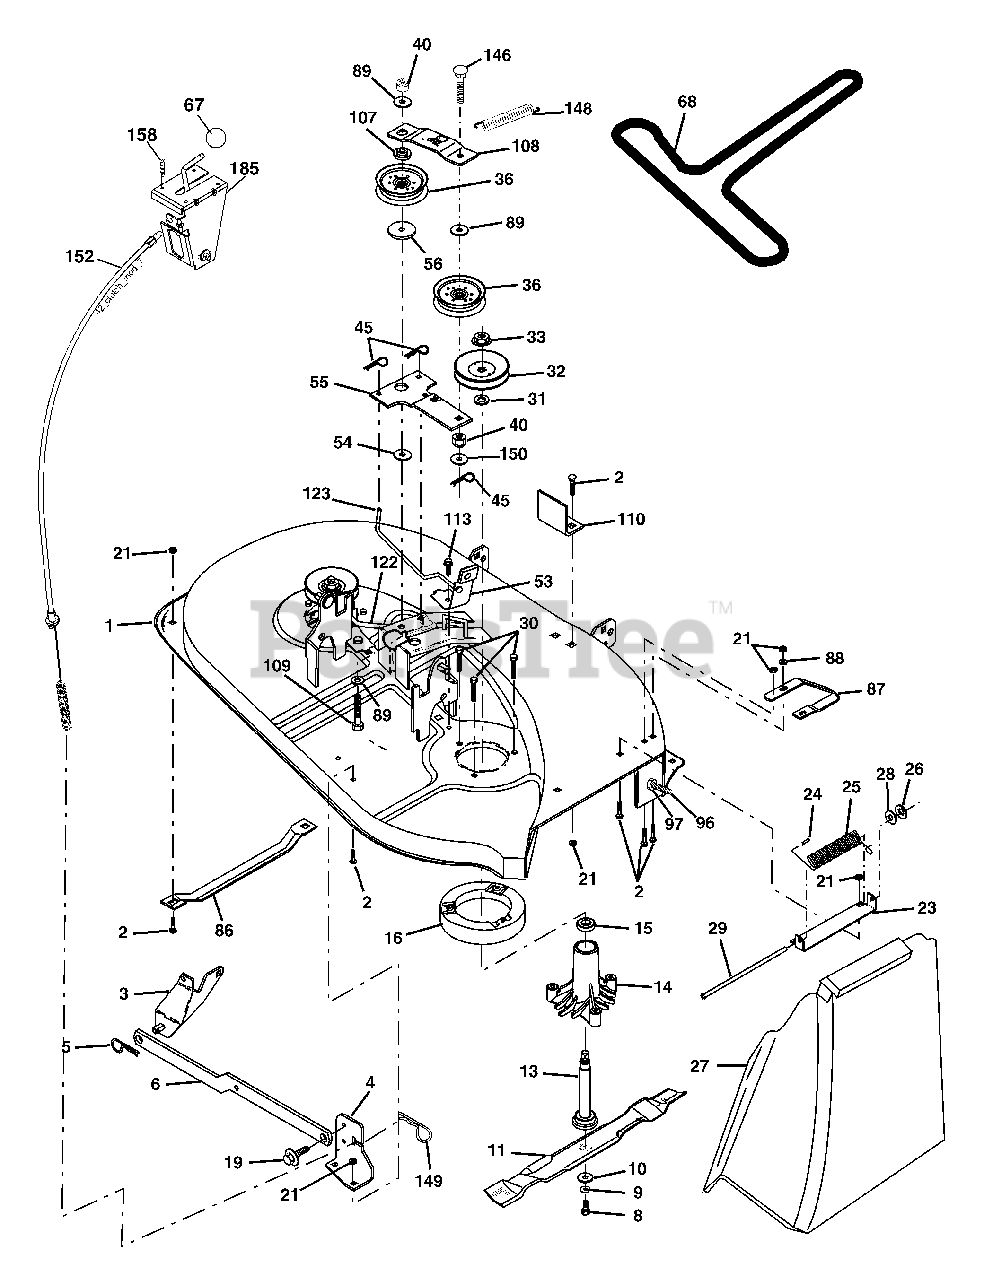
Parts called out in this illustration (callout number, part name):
1	Mower Housing Assembly
2	Bolt Carriage 5/16-18 x 3/4
3	Bracket Asm Fr. Sway Bar
4	Bracket Deck Sway Bar 38"/42"
5	Retainer Spring
6	Bar Sway Deck
8	Bolt 3/8-24 x 1.25 Gr. 8
11	Blade Mower
13	Shaft Assembly, Mandrel, Vented
14	Housing, Mandrel, Vented
15	Bearing, Ball, Mandrel
18	Blade Rdhd Sqnk 5/16-18 x 5/8
19	Bolt, Shoulder
20	Baffl e Vortex Front
21	Nut
23	Bracket, Mower Deflector
24	Cap, Sleeve
25	Spring, Torsion, Deflector
26	Nut, Push
27	Shield, Deflector
29	Rod, Hinge
30	Screw Thdrol.
31	Washer, Spacer
32	Pulley, Mandrel
33	Nut, Toplock
36	Pulley, Idler, Flat
37	Pulley, Idler Flat
40	Nut, Crownlock 3/8-16 unc
45	Retainer
53	Brake Assembly
55	Idler Arm Assembly
56	Spacer, Retainer
67	Knob
68	V-Belt
72	Spring Brake Return
89	Washer 13/32 x 13/16 x 11 Ga.
107	Spacer Retainer
108	Stiffener, Idler Arm
122	Rod, Brake LH
123	Rod, Brake RH
144	Keeper Belt Idler Tension
148	Spring Return Idler
149	Retainer Spring Yellow
150	Washer 9/32 x 3/4 x 10 Ga.
152	Clutch Cable 38"
158	Screw Hex Thd Cut 1/4-20 x 1/2
185	Head Asm Cable Clutch
186	Screw Hex Wsh Thdrol 3/8-16 x 2-3/4
187	Keeper Belt M Shape
188	Bolt Carriage Idler
189	Brake Stand
190	Brake Arm
191	Brake Spacer
192	Brake Assembly
193	Keeper Belt Rh Mandrel
194	Brake Guard
195	Washer 13/32 x 2 x 10 Ga.
